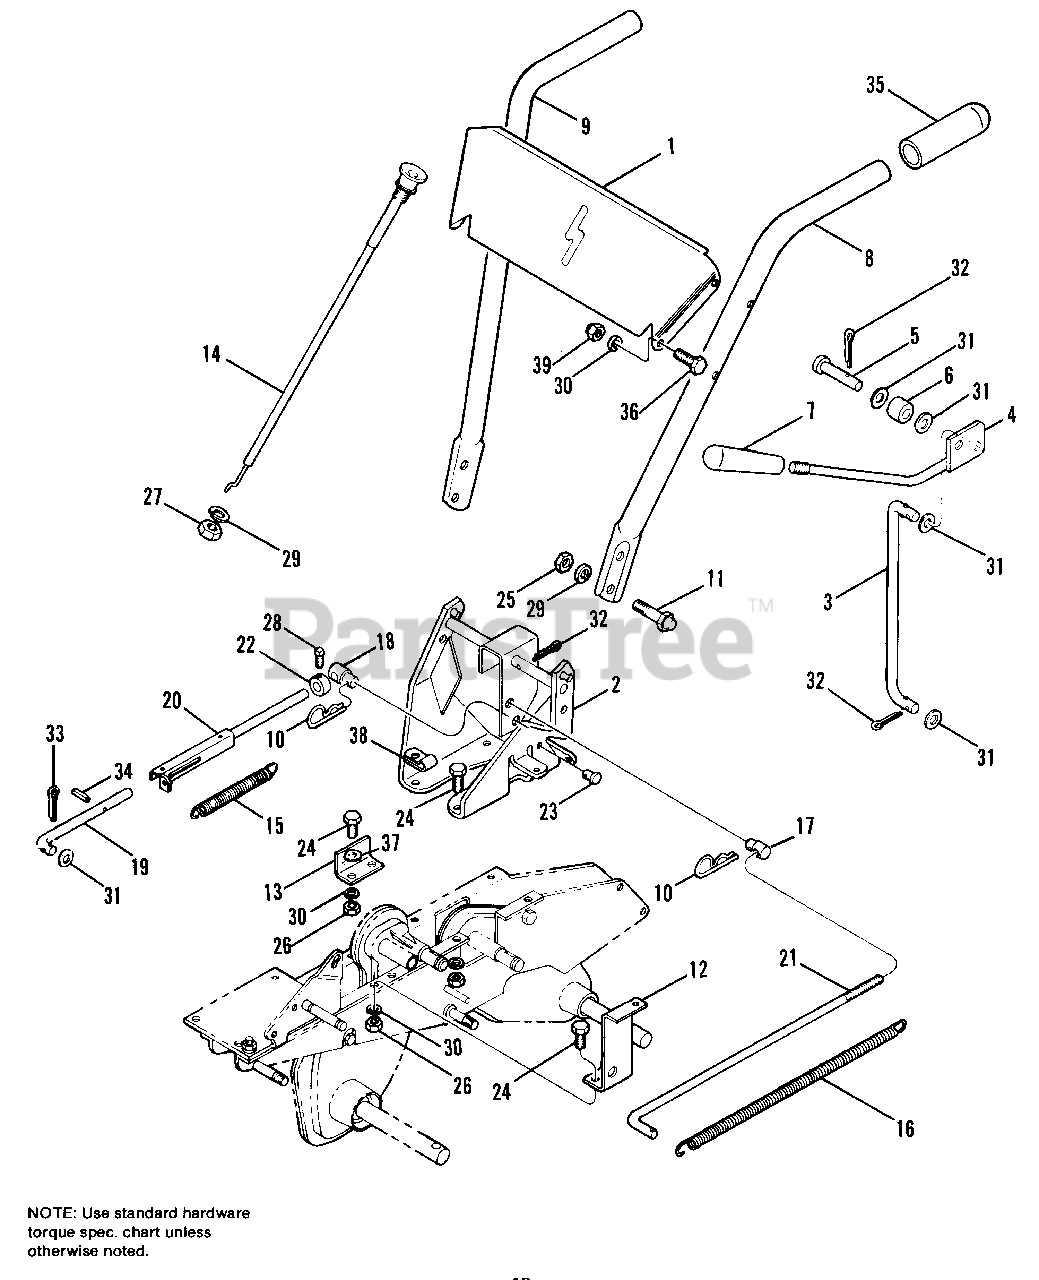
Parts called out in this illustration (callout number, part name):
1	HANDLE PANEL & DECAL ASSEMBLY
2	HANDLE SUPPORT ASSEMBLY
3	CONTROL LINK
4	CLUTCH HANDLE ASSEMBLY
5	CLEVIS PIN
6	RUBBER SPACER
8	HANDLE TUBE-L.H.
9	HANDLE TUBE-R.H.
10	SPRING CLIP
11	BOLT, Hex Hd., 3/8-16 x 1
12	BRACKET ASSEMBLY
13	PIVOT BRCKET
14	THROTTLE CONTROL
16	SPRING-Wheel Drive
19	TINE DRIVE LINK
20	REAR TINE DRIVE LINK ASSEMBLY
21	WHEEL DRIVE LINK
22	STOP COLLAR
23	CLEVIS PIN
24	CAP SCREW, Hex Hd. 5/16-18 x 3/4" Plated
25	NUT, Hex 3/8-16 Plated
26	NUT, Hex 5/16-18 Plated
27	NUT, Hex 3/8-24 Plated
28	SETSCREW, Sq. Hd. Cup Pt. 1/4-28 x 1/4" Plated
29	WASHER, Spring Lock 3/8 Plated
30	WASHER, Spring Lock 5/16 Plated
31	WASHER, Flat SAE 3/8 Plated
32	PIN, Cotter 3/32 x 3/4" Plated
33	PIN, Cotter 1/8 x 3/4" Plated
34	PIN, Roll 1/8 x 5/8" Heat Treated
36	CAP SCREW, Hex Hd. 5/16-18 x 1-3/4" Plated
37	WASHER, Flat SAE 5/16 Plated
38	CABLE CLAMP
39	NUT, Cone Lock, 5/16-18 Plated
